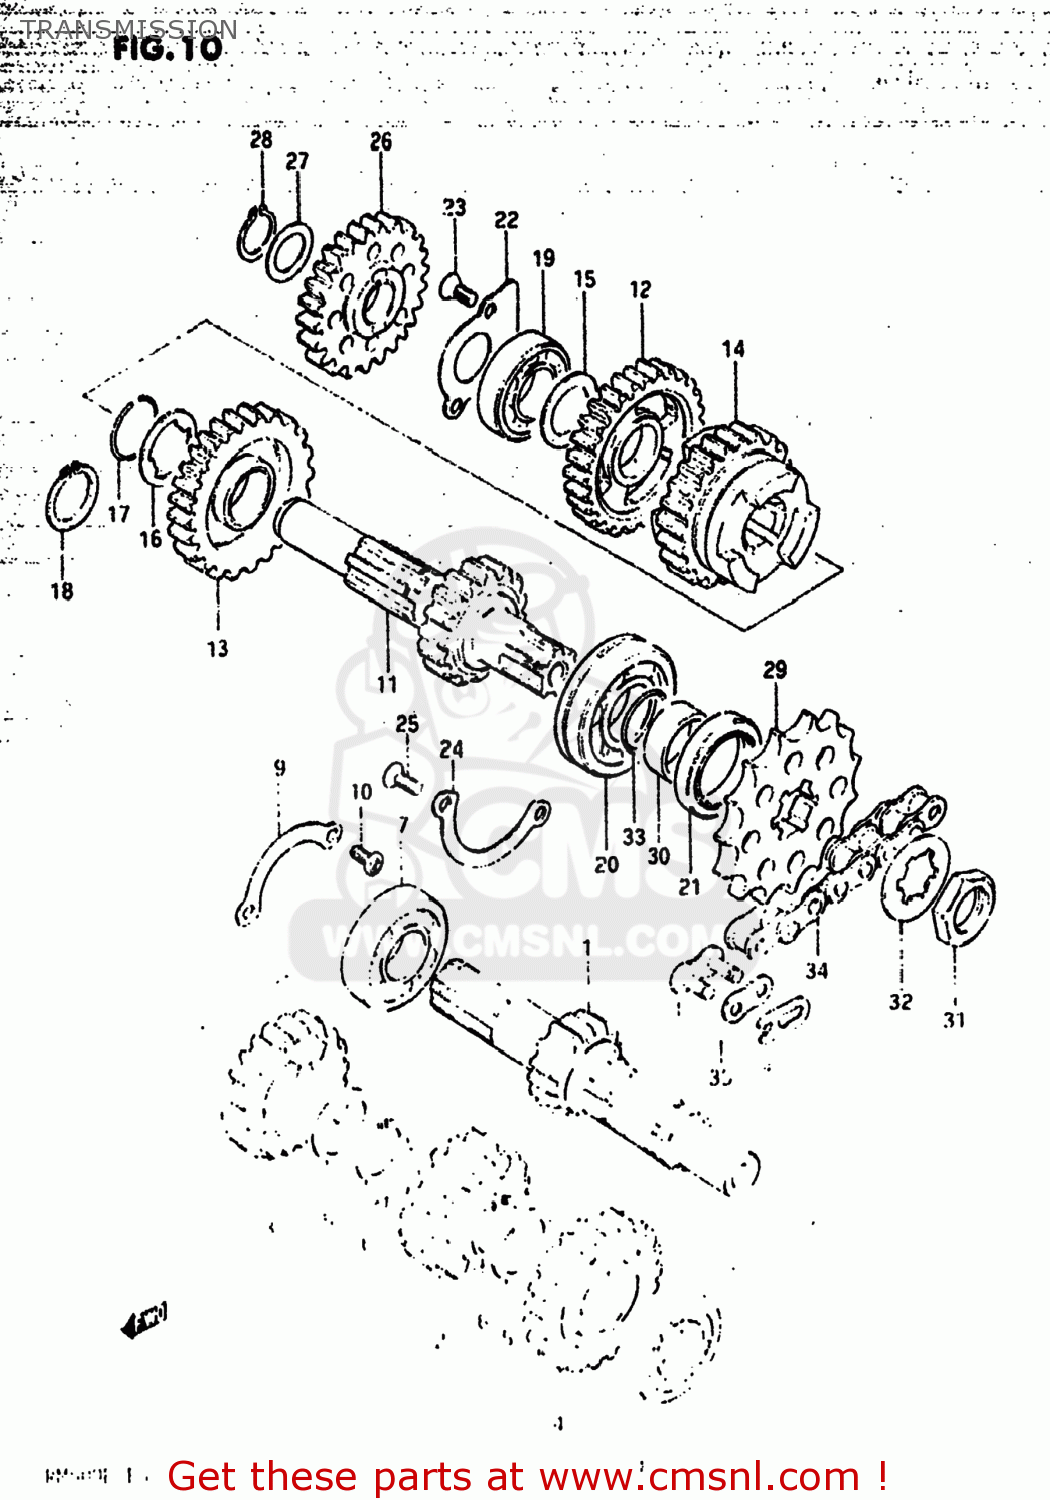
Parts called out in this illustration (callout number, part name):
1	SHAFT,COUNTER
2	GEAR,SECOND DRIVE
3	GEAR,THIRD DRIVE
4	GEAR,FOURTH DRIVE
5	WASHER
6	CIRCLIP
7	BEARING
8	BEARING, LH
9	RETAINER,BEARING
10	SCREW 6X12
11	SHAFT,DRIVE
12	GEAR,FIRST DRIVEN
13	GEAR,SECOND DRIVEN
14	GEAR,THIRD DRIVEN
15	WASHER
16	WASHER
17	CIRCLIP
18	CIRCLIP
19	BEARING
20	BEARING(28X58X16)
21	SEAL,OIL(35X45X6)
22	RETAINER,DRIVESHAFT
23	SCREW
24	PLATE,DRIVESHAFT BEARING
25	SCREW
26	GEAR,KICK STARTER IDLE
27	WASHER,THRUST
28	CIRCLIP
29	SPROCKET,ENGINE(NT:13)
30	SPACER(28X35X11.4)
31	NUT
32	WASHER,LOCK
33	O RING(D:1.5,ID:27.7)
34	CHAIN ASSEMBLY,DRIVE
35	JOINT ASSEMBLY,CHAIN
